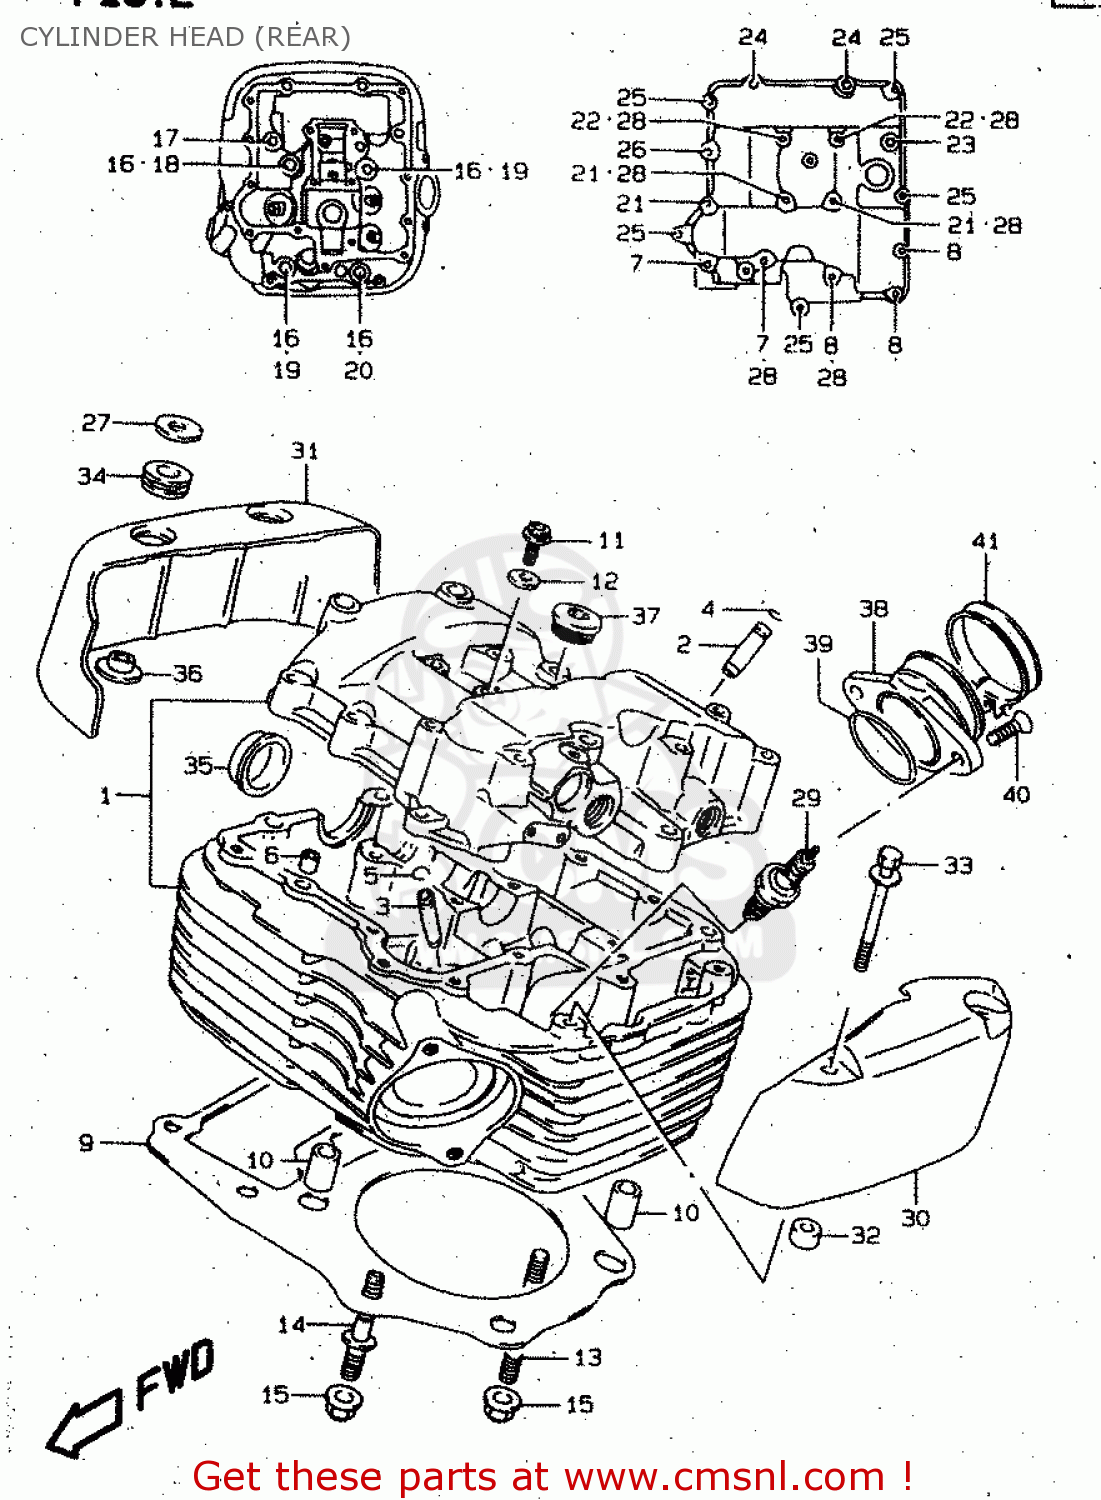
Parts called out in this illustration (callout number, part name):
1	HEAD ASSEMBLY,CYLINDER,REAR
2	GUIDE,INTAKE VALVE
3	GUIDE,INTAKE VALVE
4	RING,SNAP
5	RING,SNAP
6	PIN(6.2X8X11)
7	BOLT(6X60)
8	BOLT(6X55)
9	GASKET,CYLINDER HEAD RR (NAS)
10	PIN
11	BOLT
12	GASKET(6.2X13X1.2) (NAS)
13	BOLT,STUD
14	BOLT,STUD
15	NUT
16	WASHER (10.5X22X2.3)
17	BOLT(8X57)
18	BOLT(10X180)
19	BOLT(10X190)
20	BOLT(10X215)
21	BOLT(6X50)
22	BOLT(6X45)
23	BOLT(8X130)
24	BOLT(8X268)
25	BOLT
26	BOLT
27	WASHER(8.5X24X1.6)
28	GASKET(5.8X13X1.2) (NAS)
29	SPARK PLUG DP7EA-9
30	CAP,CYLINDER HEAD COVER RL
31	CAP,CYLINDER HEAD COVER RR
32	CUSHION,R CAP
33	BOLT
34	CUSHION
35	PLUG(OD:30)
36	BUSH
37	PLUG,22X11
38	PIPE ASSY,INTAKE RR
39	O RING(D:1.9,ID:40.7)
40	SCREW
41	CLAMP
